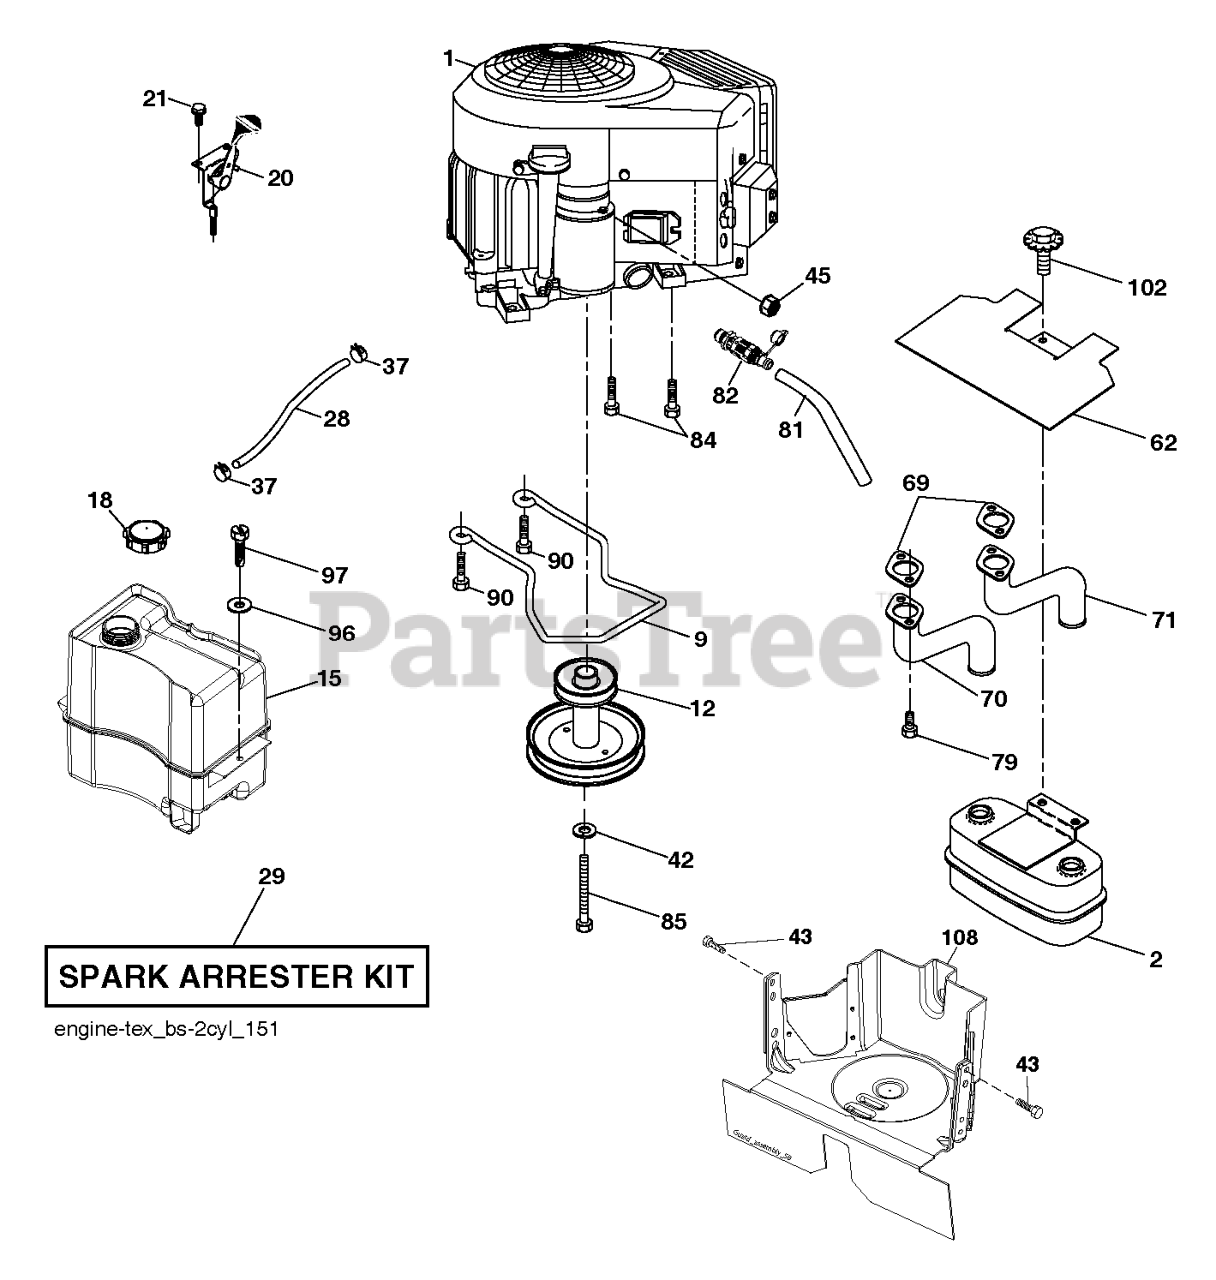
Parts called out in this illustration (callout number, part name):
2	MUFFLER.ASM.TWIN.MNTG.BRACKET
9	KEEPER.BELT.ENG.4.25"2.BLT.431
12	ENGINE.PULLEY
15	TANK.ASSEMBL.2.5GAL.NON-EPA
18	CAP ASM.FUEL.2.25"FR.
20	THROTTLE.COBRA.38"READSTART.BK
21	SCREW.#10 X 0.750.BOS
28	LINE.FUEL.20
29	KIT.SPARK ARRESTOR 794945 B&S
37	HOSE CLAMP
42	WASHER 7/16 LOCK
43	SCREW 5/16-18X1
45	NUT
62	SHIELD.HEAT.MUFFLER
69	GASKET.MUFFLER
70	EXHAUST.TUBE.LH.BS/TWIN
71	EXHAUST.TUBE.RH.B&S.TWIN.INTEK
79	SCREW.SOCKET.HEAD.5/16-18
81	TUBE, DRAIN OIL ASM.
82	VALUE.OIL.DRAIN
84	SCREW.3/8-16
85	BOLT.HEX.7/16-20X4.GR5.1.5BLUE
90	SCREW 3/8-16X1
97	SCREW HEXWSHR 1/4-20X3/4
102	SCREW
108	COVER PULLEY
